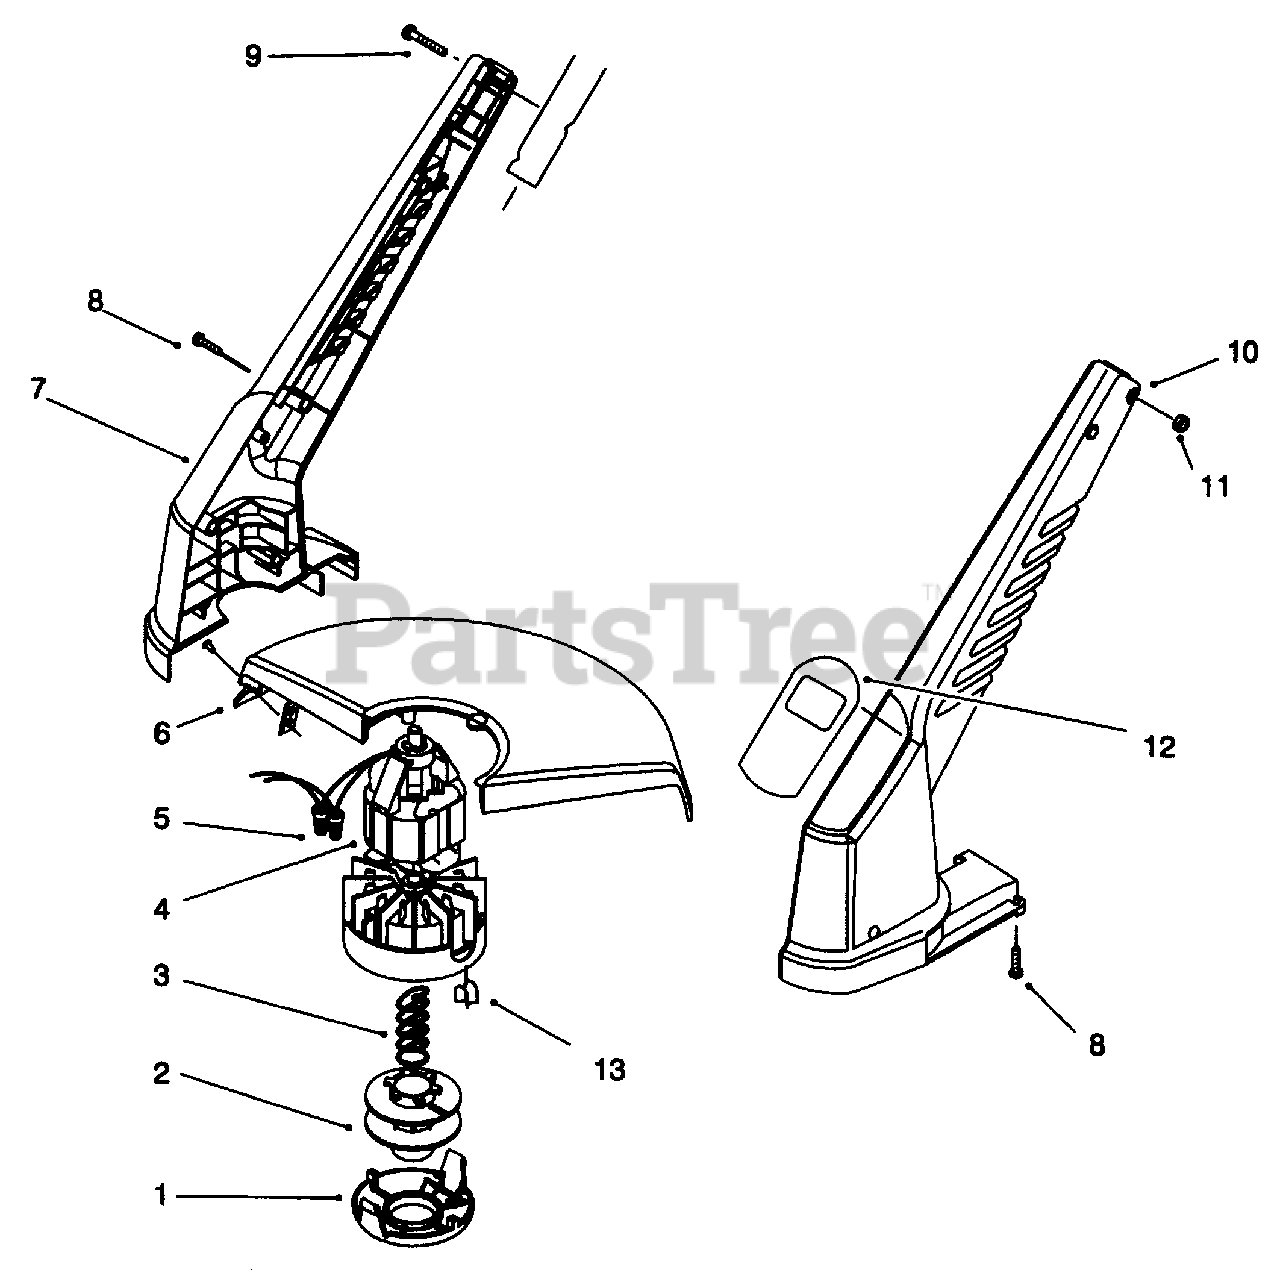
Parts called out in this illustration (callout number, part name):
4	Motor Assembly (Incl. Ref. #13)
5	Connector-Wire Nut
6	Shield-14"
7	Housing R.H.
8	Screw-Pan Hd.
9	Screw-Pan Hd.
10	Housing L.H.
12	Decal-14" Trimmer
